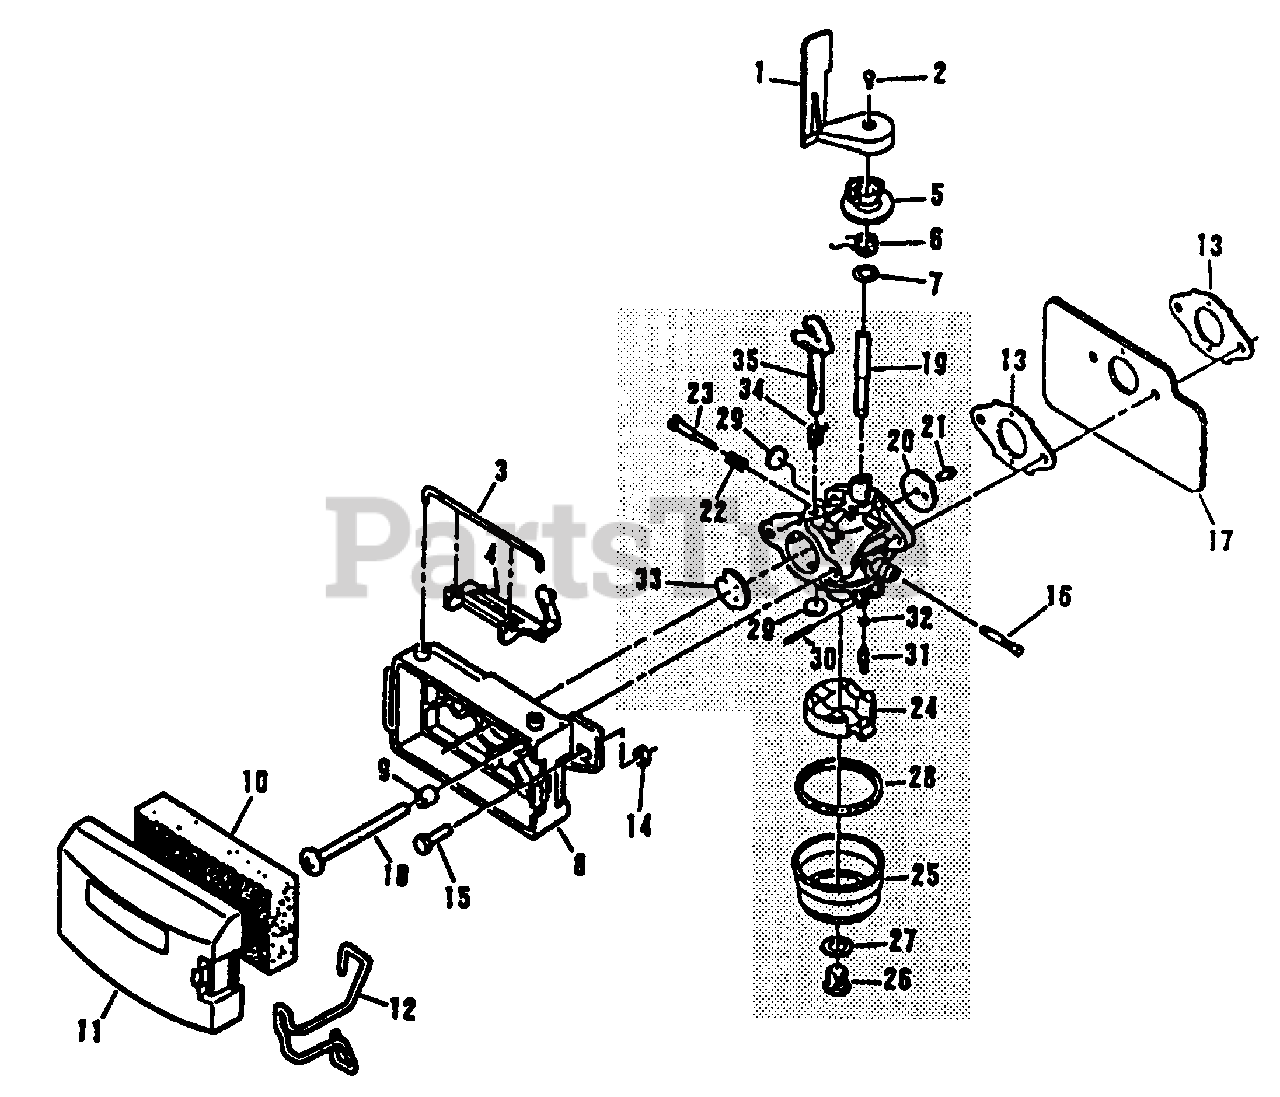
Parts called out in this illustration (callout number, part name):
1	Air Vane
2	Screw-Air Vane
3	Retainer-Speed Control Lever
4	Governor Control Lever
5	Collar
6	Spring
7	Washer
8	Air Filter Base
9	Spacer-Air Filter Base
10	Air Filter Element
11	Air Filter Cover
12	Air Filter Cover Retainer
13	Gasket-Carburetor to Crankcase Cover
14	Nut, Hex-Throttle Cable
15	Screw-Throttle Cable
16	Fuel Filter
17	Heat Shield
18	Screw-Carburetor Mounting
19	Throttle Shaft
20	Throttle Valve
21	Screw-Throttle Valve
22	Spring-Idle Needle
23	Idle Needle
24	Float Assembly Kit
25	Fuel Bowl
26	Screw-Bowl Retainer
27	Bowl Retainer Gasket
28	Fuel Bowl Gasket
29	Plug-Welch
30	Float Shaft
31	Inlet Needle Valve
32	Valve Seat
33	Choke Valve
34	Choke Return Spring
35	Choke Shaft
